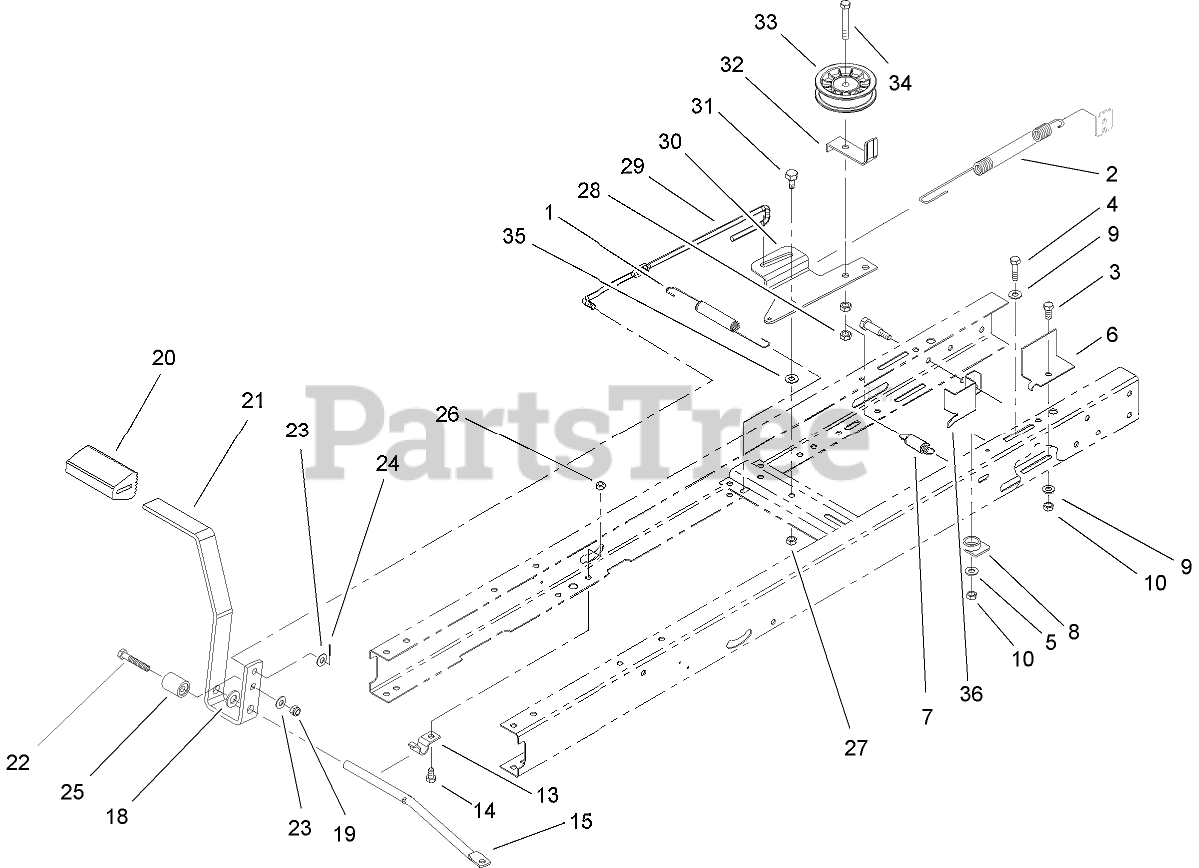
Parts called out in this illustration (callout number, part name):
1	SPRING-EXTENSION
2	SPRING-BRAKE
3	SCREW-HH
4	SCREW-HH
5	WASHER-PIVOT
6	BRACKET-BELT, GUIDE
7	SPRING-EXTENSION
8	GUIDE-CABLE
9	WASHER-PLAIN
10	NUT-LOCK, NI
13	CLAMP-PIVOT, SHIFT
14	SCREW-HH
15	ROD-PIVOT, PEDAL
18	WASHER-FLAT
19	NUT-LOCK, NI
20	PAD-PEDAL
21	PEDAL-CLUTCH/BRAKE, HYDRO
22	SCREW-HH
23	WASHER-PLAIN
24	PIN-COTTER
25	SPACER
26	NUT-LOCK, NI
27	NUT-LOCK, NI
28	NUT-LOCK, NI
29	ROD-CLUTCH/BRAKE
30	ARM-IDLER
31	BOLT-SHOULDER
32	GUIDE-IDLER, BELT
33	PULLEY-IDLER
34	SCREW-HH
35	WASHER-PIVOT
36	BRACKET-BELT, GUIDE
